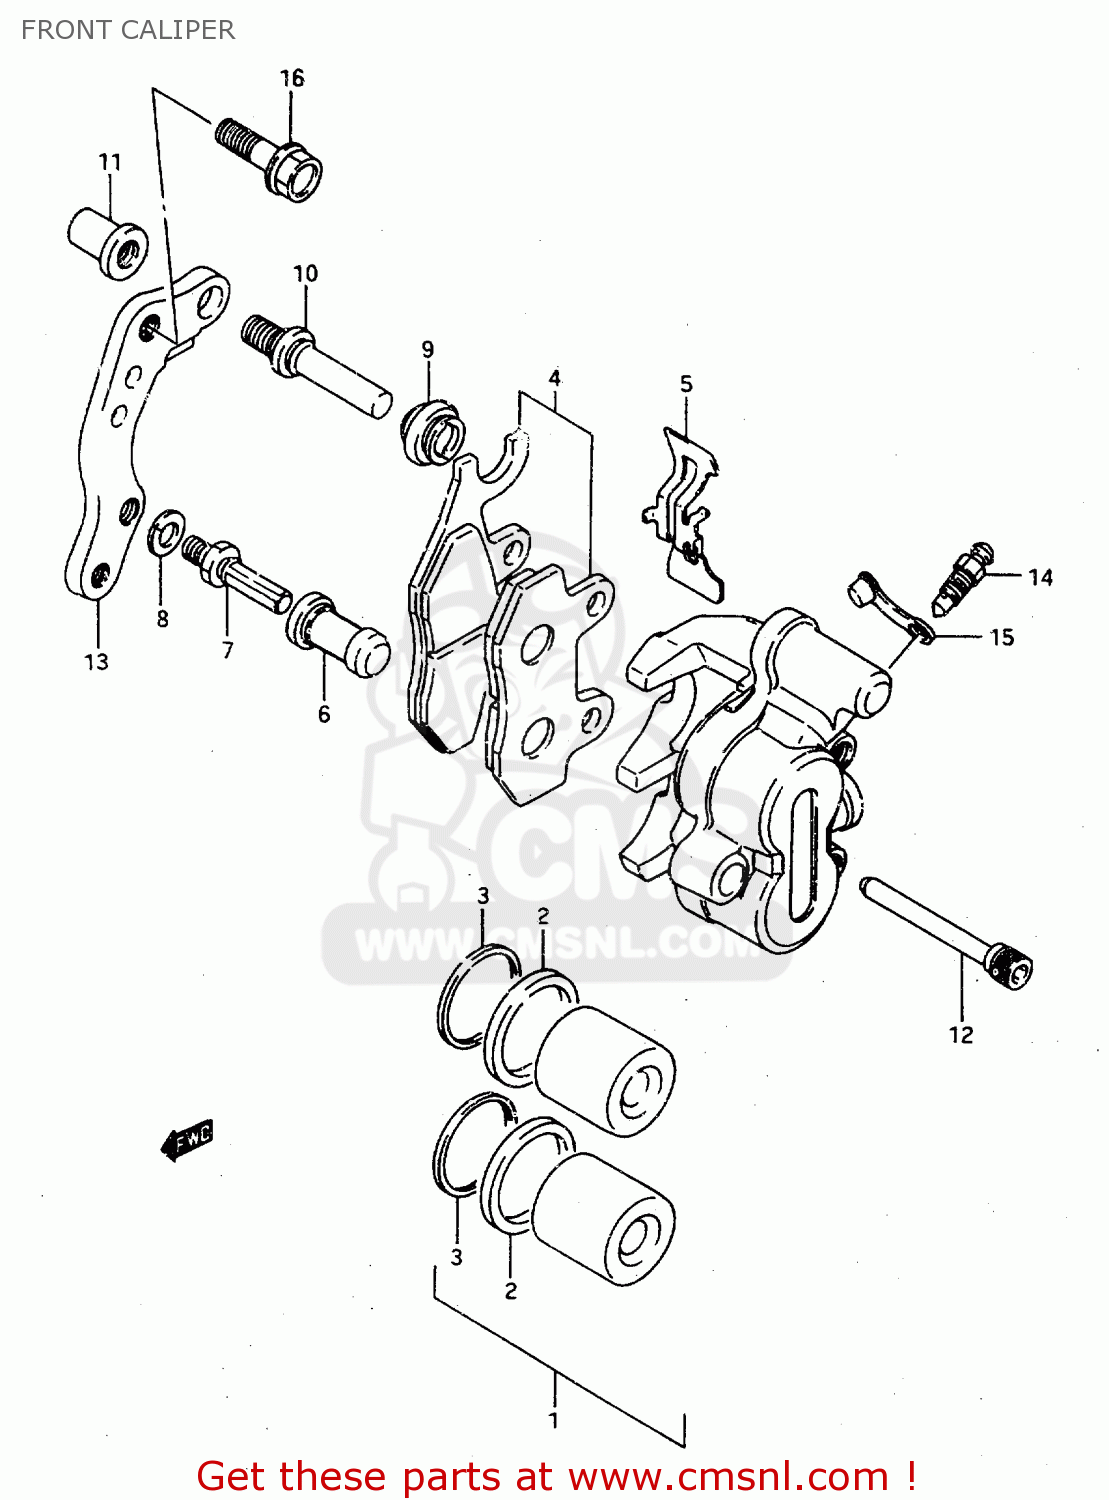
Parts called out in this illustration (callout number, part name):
1	PISTON SET
2	SEAL,PISTON
3	SEAL,DUST
4	PAD SET (NAS)
5	SPRING
6	BOOT
7	BOLT,PIN
8	WASHER,WAVE
9	BOOT
10	PIN,SLIDE
11	NUT
12	PIN,HOLDER
13	BRACKET
14	BLEEDER
15	CAP,BLEEDER
16	BOLT(8X29)
